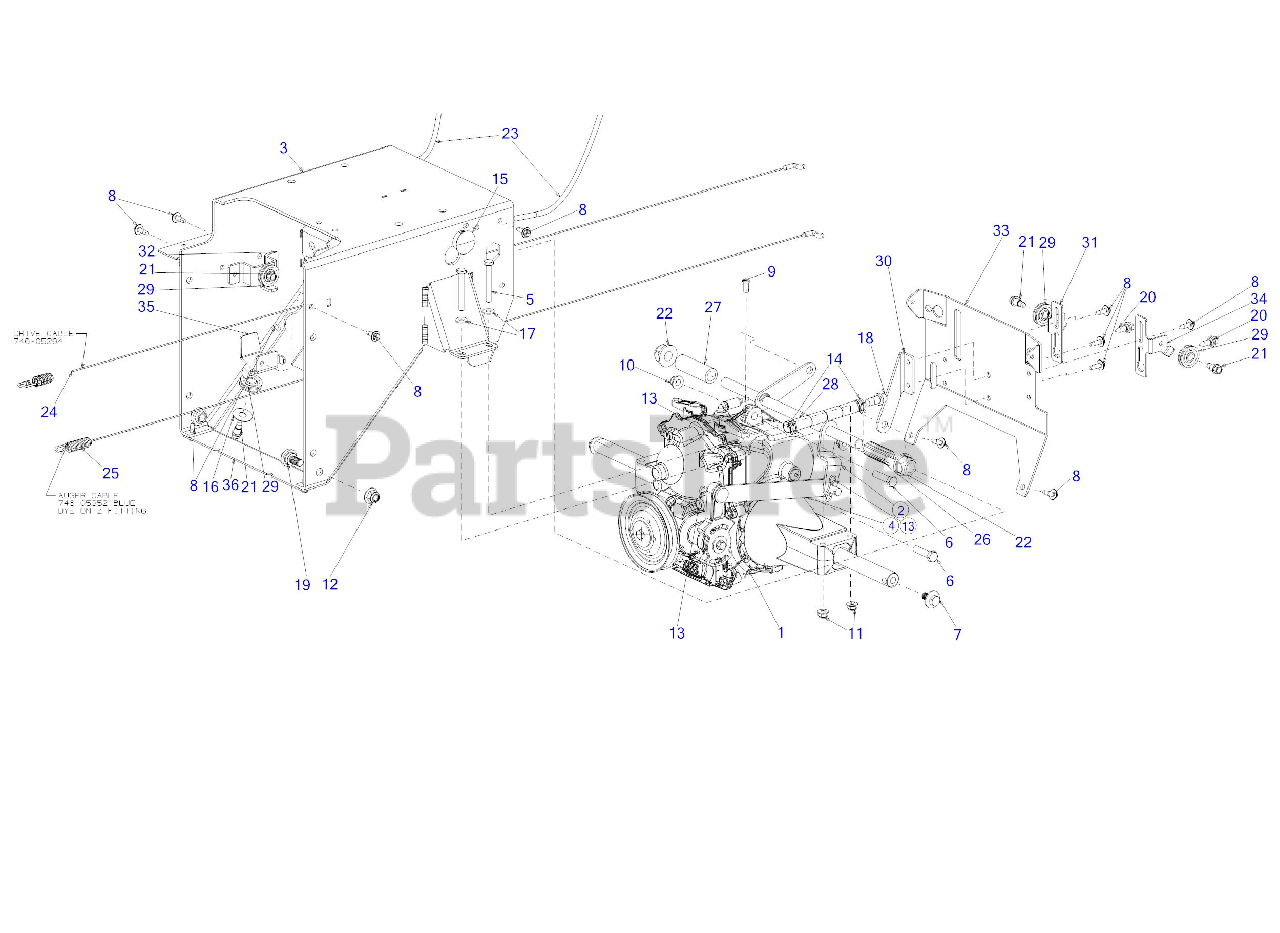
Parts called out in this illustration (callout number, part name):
1	HYDRO TRANSMISSION ASSEMBLY
2	CONTROL SHAFT ASSEMBLY
4	SHIFT LINKAGE
5	SCREW 1/4-20 x 2 GR5
6	SCREW 5/16-18 x 1.25 GR5
7	SCREW 5/16-24 x .750 GR5
8	SCREW M6-1 x .625
9	CLEVIS PIN .25 x .50
10	FLANGE LOCK NUT 5/16-18
11	FLANGE LOCK NUT
13	BOW TIE COTTER PIN 1/4-5/16
14	HOSE CLAMP
15	PLASTIC PLUG
16	FLAT WASHER
17	FLAT WASHER .271:.630:.065
19	SHOULDER SCREW .625X.165X3/8-16
20	SHOULDER SCREW
21	SHOULDER SCREW
22	FLANGE BEARING
23	STEERING CABLE
24	WHEEL DRIVE CABLE 48.31"
25	AUGER DRIVE CABLE 48.23"
26	SPACER-.491 ID x 1.67 LG
27	SLEEVE SPACER .525 X .78 X 2.36
28	FUEL HOSE LOW PERMEATION
29	CABLE GUIDE ROLLER
31	CABLE IDLER BRACKET (RH)
34	CABLE IDLER BRACKET (LH)
